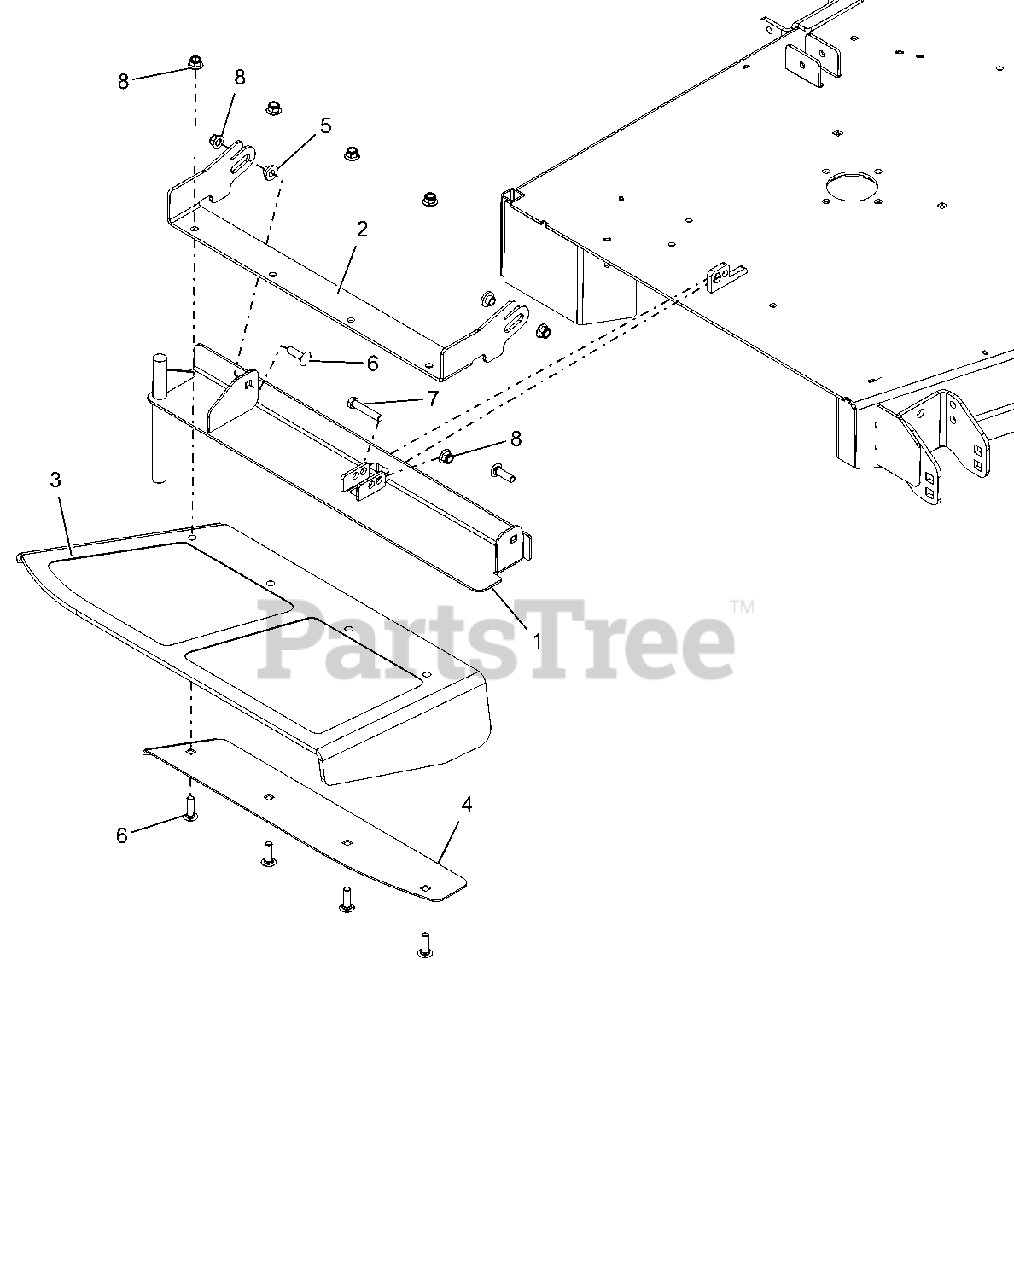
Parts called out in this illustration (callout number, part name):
1	WLDMT, 72" DISCH CHUTE MOUNT
2	BRKT, 72" CHUTE MTG - RED
3	CHUTE, 72" FORMED RUBBER DISCHARGE
4	PLATE, 72" DICH CHUTE CLAMP
5	BSHG, FLG .385 X .500 X .875 X .406
6	BLT-RHDSSQNK .38-16X1.25 G5YZ
7	BLT-HEX .38-16X2.00 GR5 YWZC
8	NUT-LK-NYL-FLG .38-16 YWZC
